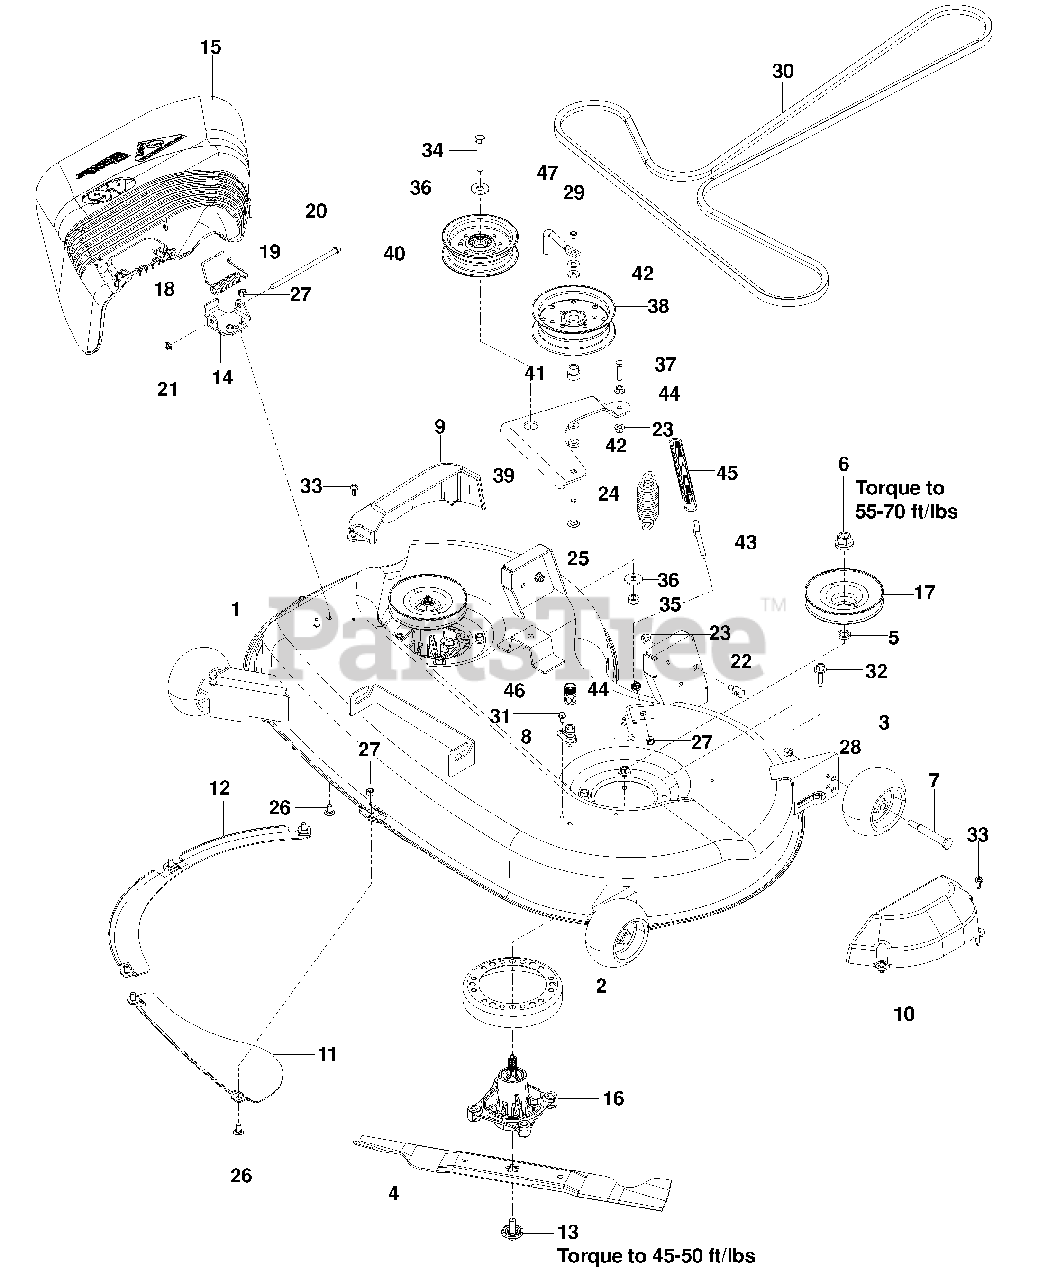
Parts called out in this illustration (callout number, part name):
1	DECK w/ SAFETY DECALS
2	STRIPPER,UNIVERSAL
3	WHEEL, GAUGE
4	BLADE, HI-LIFT
5	WASHER, SPACER
6	NUT 9/16 TOP CNTRLK
7	BOLT, SHOULDER
8	WASHOUT PORT
9	SHIELD, BELT RH
10	SHIELD, BELT LH
11	BAFFLE, FRONT
12	BAFFLE, FRONT RH
13	BOLT, WASHER
14	BRACKET, DEFLECTOR
15	SHIELD, DEFLECTOR
16	CUTTER HOUSING
17	PULLEY, DECK
18	SPRING, TORSION
19	CAP, SLEEVE
20	ROD, HINGE
21	PUSHNUT
22	STUD w/ ANTI-ROTATE
23	NUT 5/16-18 HEX FLG NYLOC
25	BOLT 3/8-16 x 2 1/2 CARRIAGE
26	BOLT 5/16-18 x 3/4 RD HD
27	NUT 5/16-18 HEX NYLOC
28	NUT 3/8-16 HEX NYLOC
29	NUT 3/8-16 HEX NYLOC, JAM
30	BELT, DECK
31	BOLT 1/4-20 x 1/2 HWST
32	SCREW 5/16-18 x WSH HD
33	SCREW 1/4-20 x 5/8 TRDROLL
34	BOLT, HEX HD 7/16-14 x 2 1/2
35	NUT 7/16-14 HEX NYLOC
36	WASHER 7/16
37	BOLT 5/16-18 x 1 1/4 HEX HD
38	PULLEY, IDLER
39	ARM, IDLER
40	PULLEY, IDLER SPEC. HUB
41	IDLER BUSHING
42	WASHER 3/8
43	EYE BOLT 5/16 x 3 1/2
44	NUT 5/16-18 HEX WHIZLK
45	SPRING, DECK BELT
46	COUPLING, CONNECT
47	BELT KEEPER
